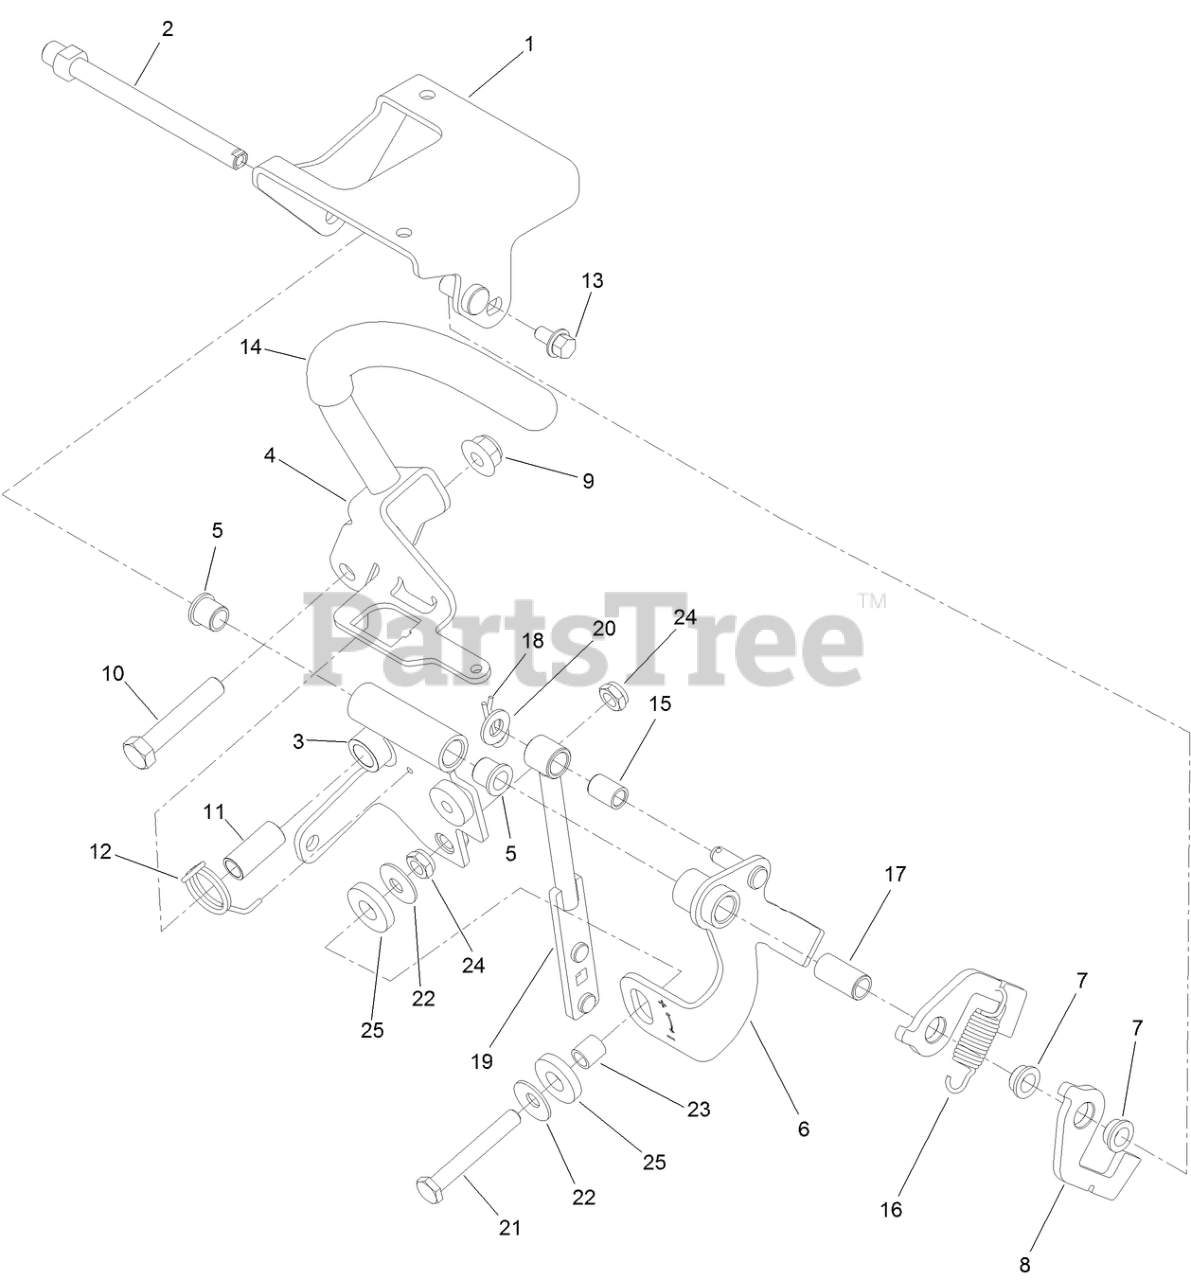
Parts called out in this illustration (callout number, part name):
1	BRACKET-MOUNT, LH
2	PIN-PIVOT
3	MOTION CONTROL ASM LH
4	LH LEVER ASM
5	BEARING
6	MOTION CONTROL ASM LH
7	BUSHING-FLANGED NYLON
8	PLATE-SPRING
9	NUT-HF, NI
10	SCREW-HH
11	BEARING-SLEEVE
12	SPRING-TORSION
13	SCREW-HHF
14	GRIP-HANDLE
15	BUSHING
16	SPRING-EXTENSION
17	BUSHING
18	PIN-COTTER
19	CONTROL ROD ASSEMBLY
20	WASHER-PLAIN
21	BOLT-TAP, HH
22	WASHER-BELLEVILLE
23	SPACER
24	NUT-LOCK, NI
25	WASHER-RUBBER
